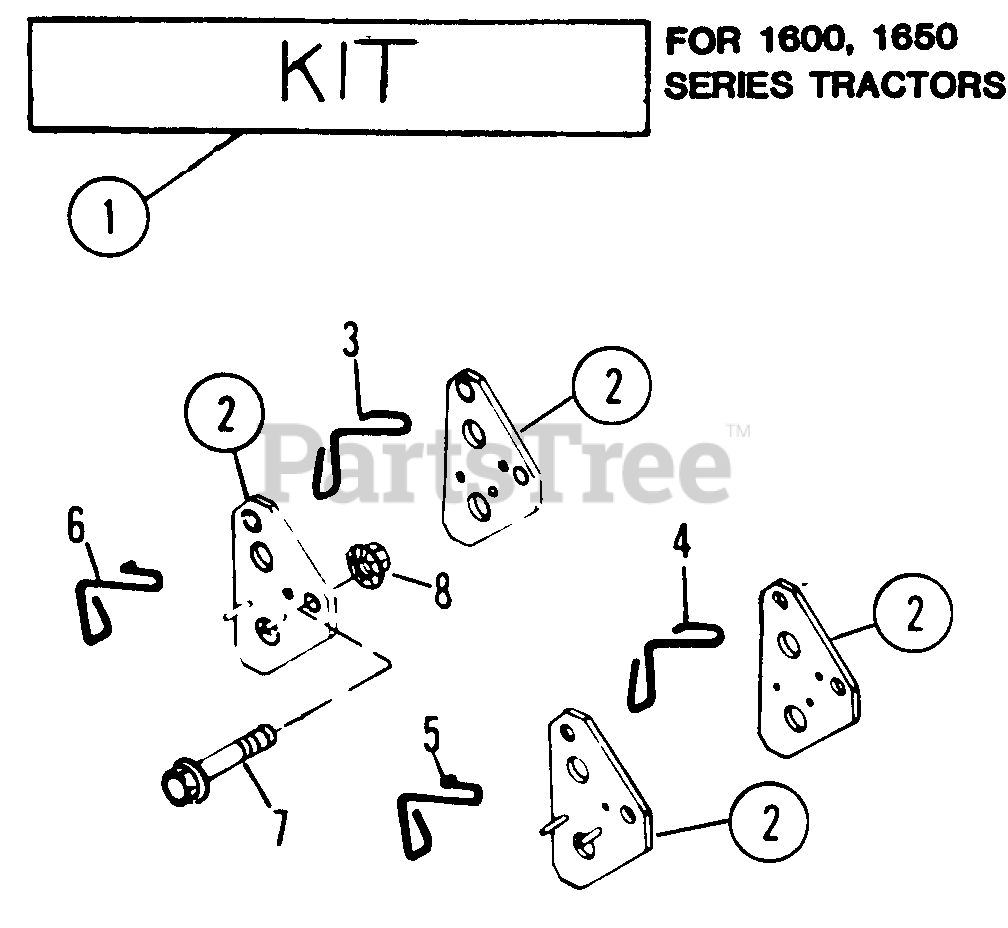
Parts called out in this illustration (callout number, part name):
1	KIT, IMPLEMENT MTG.
2	BRACKET, LINK PIVOT
3	SPRING, LEFT REAR
4	SPRING, LEFT FRONT
5	SPRING, RIGHT FRONT
6	SPRING, RIGHT REAR
7	BOLT, 5/16-18 x 1 HEX FLANGE LOCK
8	NUT, 5/16-18 HEX LOCK
